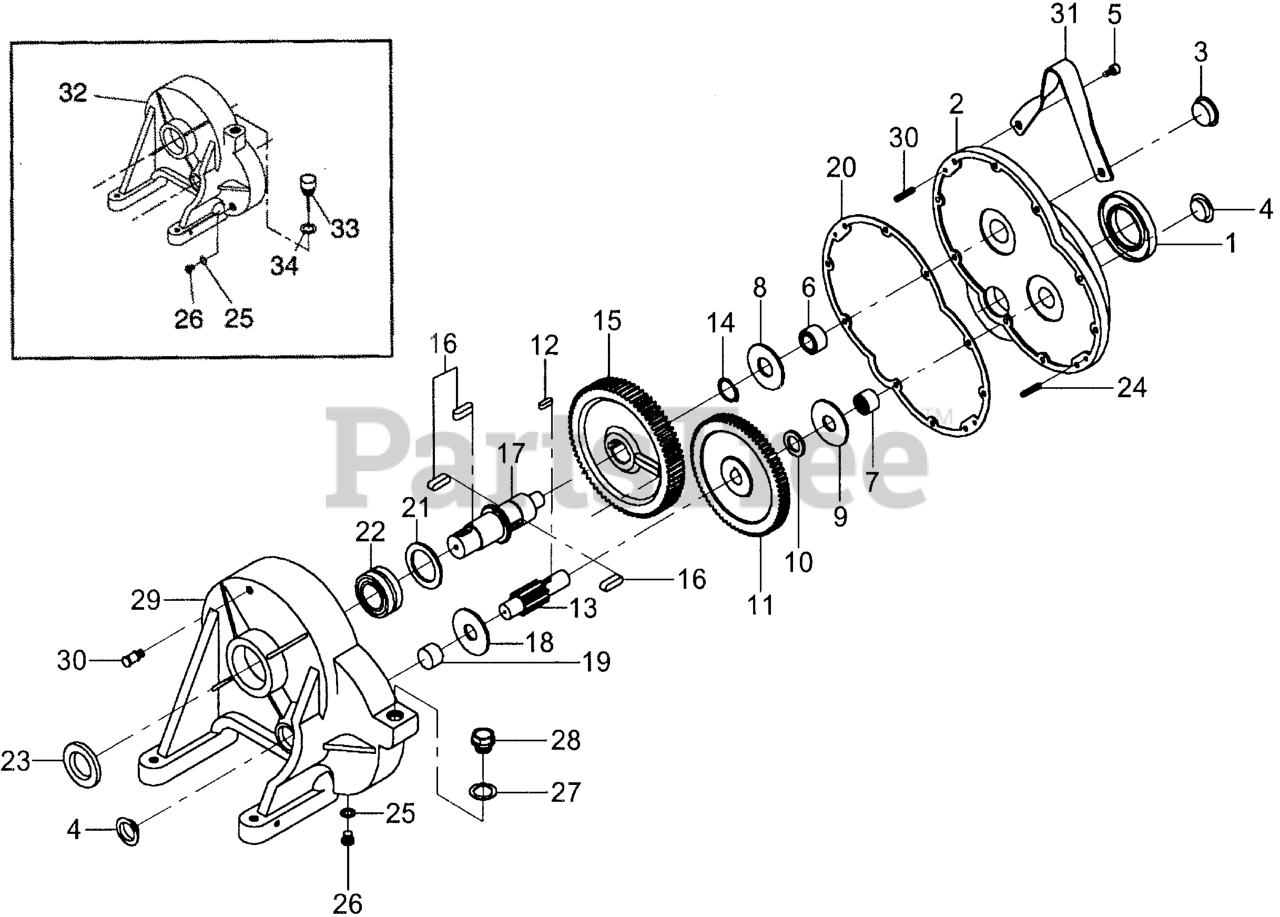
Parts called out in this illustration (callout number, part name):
1	SEAL (48X80X10)
2	COVER (ALUMINUM)
2	COVER, GEAR BOX
4	PLUG (NOT AVAILABLE)
5	SCREW, ALLEN (6X1.0X25)
7	BEARING, NEEDLE
8	WASHER, FIBER
9	WASHER, FIBER
11	GEAR
20	GASKET
20	GASKET, GEAR BOX
27	WASHER
28	PLUG
29	CASE (ALUMINUM)
31	BAIL, LIFTING *NH1* (BLACK)
32	CASE, GEAR BOX
33	DIPSTICK, OIL W/DISCHARGE VALVE
34	GASKET, DIPSTICK
